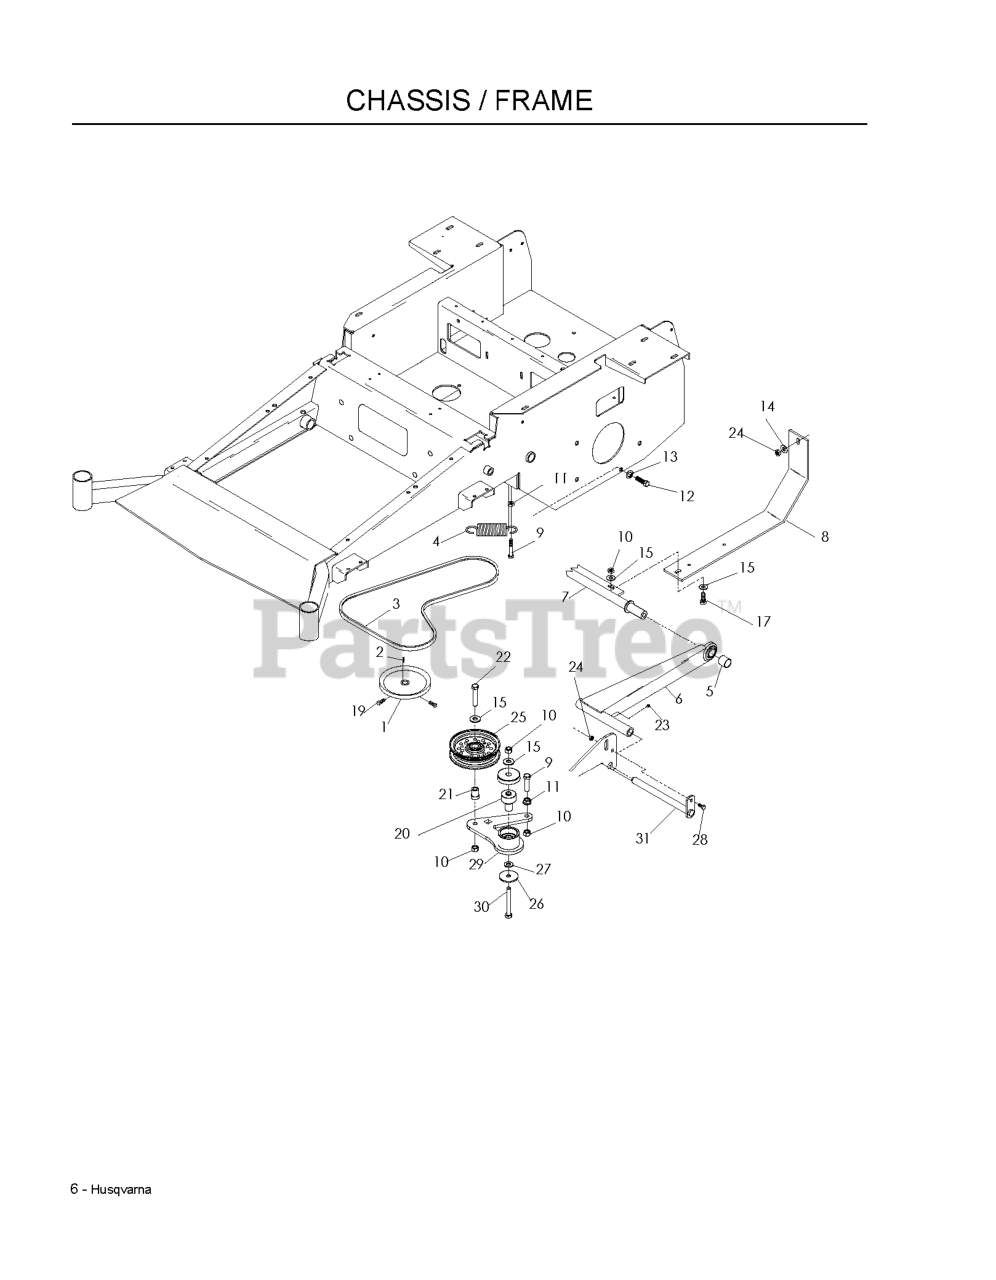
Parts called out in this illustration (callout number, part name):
2	KEY 5 MM SQ X 25 MM
3	PUMP BELT
5	SPACER, STRUT
7	CROSS SHAFT, STRUT - BLK
8	SKID PLATE
9	HCS 3/8C X 1 1/2
10	NUT 3/8-16 NYLOC
11	NUT 3/8C WHIZ
12	BLADE BOLT/WASHER
13	WASHER 7/16 LOCK
14	WASHER 5/16 FLAT
15	WASHER 3/8 FLAT
17	HCS 3/8-16X1.GRD.5.ZD
19	SCREW 5/16C X 5/8 SQ HEAD
20	PIVOT, BEARING
21	BUSHING, IDLER FLANGE
22	HCS 3/8C X 2
23	ZERK
24	NUT 5/16 NYLOC
25	IDLER PULLEY
26	WASHER, 3/8 SPEC
27	WASHER 3/8 SAE FLAT
28	HCS 5/16C X 1
29	ARM, IDLER - W/BEARINGS
30	HCS 3/8C X 3
